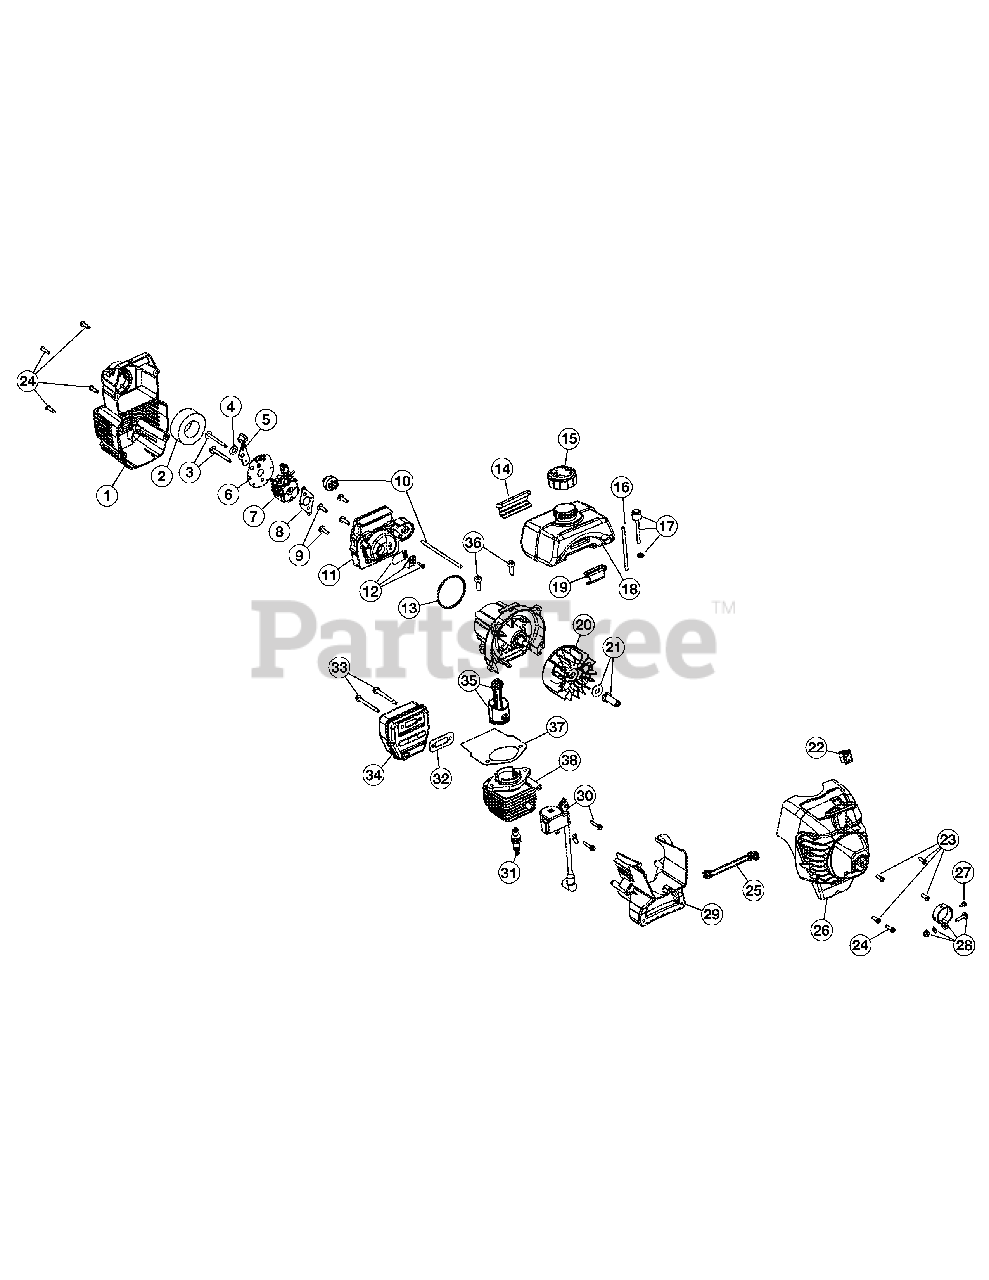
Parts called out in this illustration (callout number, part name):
1	Air Cleaner Cover Assembly
2	Air Cleaner Filter
3	Carburetor Mounting Screws
4	Wavey Washer
5	Choke Lever Assembly
6	Choke Plate
7	Carburetor Assembly
8	Carburetor Gasket
9	Carb Mount Screw
10	Primer and Hose Assembly
11	Carburetor Mount Assembly
12	Reed Assembly
13	O-Ring
14	Rear Mounting Pad
15	Fuel Cap Assembly
16	Fuel Return Line
17	Fuel Line Assembly
18	Fuel Tank Assembly
19	Front Mounting Pad
20	Flywheel Assembly
21	Square Nut Drive Assembly
22	Switch Assembly
23	Housing Screw
24	Cover Screw
25	Wire Lead
26	Starter Housing Assembly
27	Anti-Rotation Screw
28	Clamp Assembly
29	Shroud Extension and Stand
30	Module Assembly
31	Spark Plug
32	Exhaust Gasket
33	Muffler Mounting Bolt Assembly
34	Muffler Assembly
35	Piston & Rod Assembly
36	Cylinder Bolt
37	Cylinder Gasket
38	Cylinder Assembly
